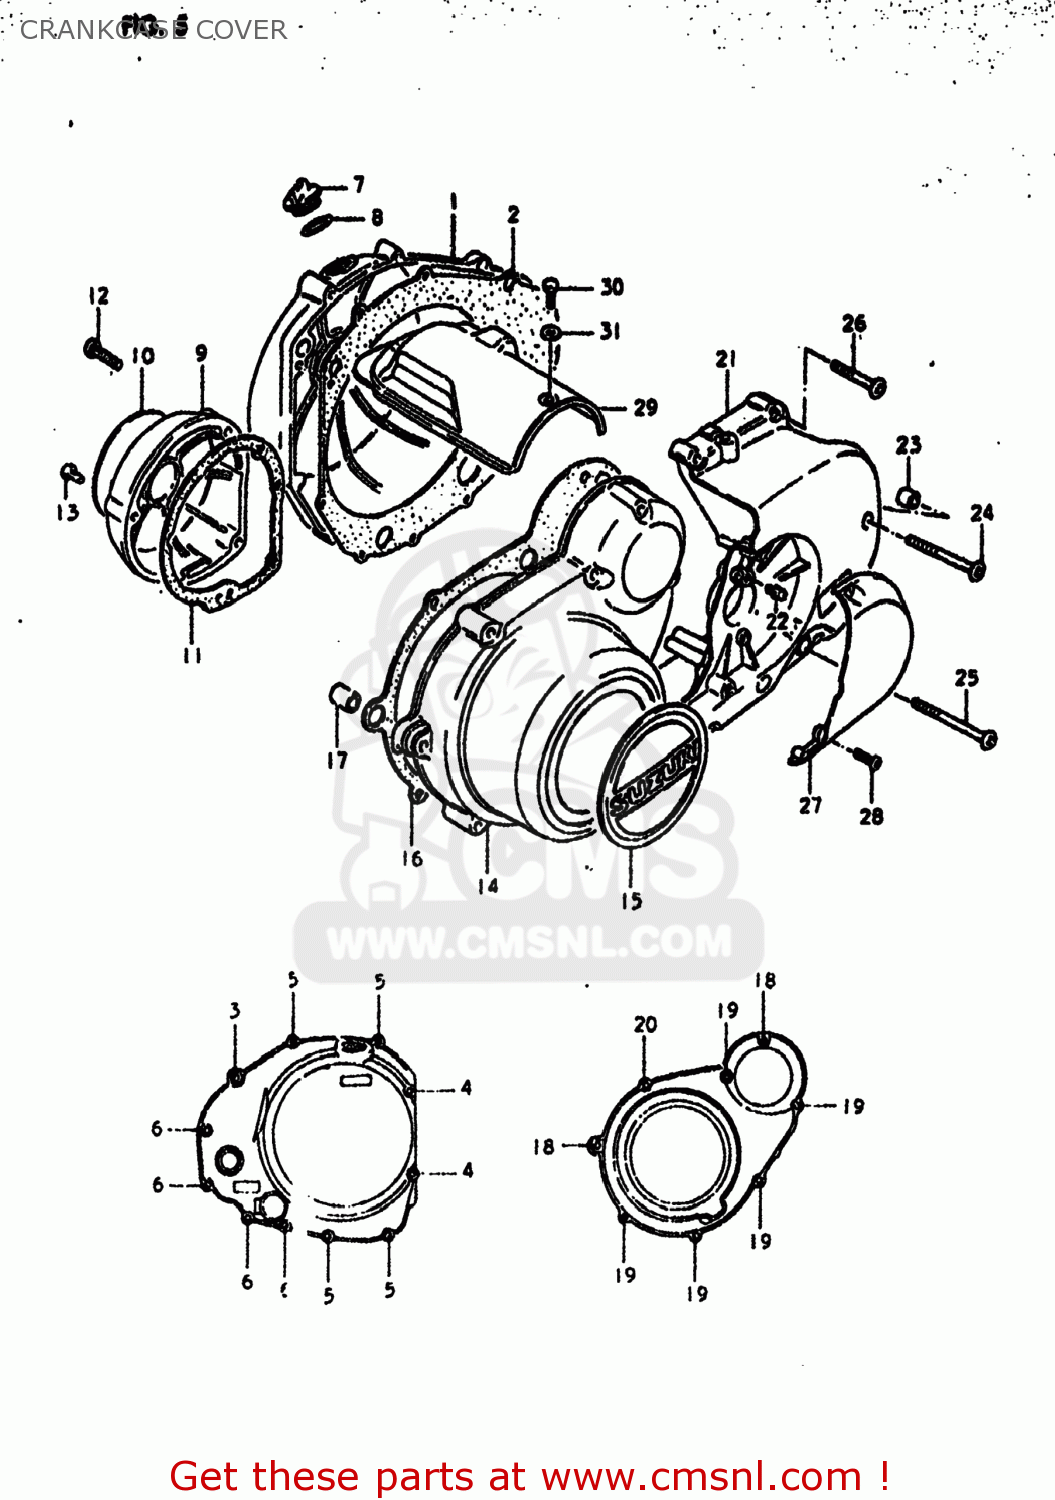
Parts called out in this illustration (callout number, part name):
1	COVER,CLUTCH
2	GASKET,CLUTCH COVER (MCA)
3	SCREW (6X35)
4	SCREW
5	SCREW
6	SCREW
7	CAP
8	O RING(D:2.2,ID:32)
9	COVER,CONTACT BREAKER
10	EMBLEM,CONTACT BREAKER COVER
11	GASKET,CONTACT BREAKER COVER (NAS)
12	SCREW
13	SCREW
14	COVER
15	EMBLEM,MAGNETO COVER
16	GASKET,MAGNETO COVER (MCA)
17	PIN
18	SCREW (6X45)
19	SCREW
20	SCREW (6X35)
21	CRANKCASE SET
22	NIPPLE
23	PIN
24	SCREW
25	SCREW 6X80
26	SCREW 6X30
27	CAP,CLUTCH RELEASE ADJUST
28	SCREW
29	COVER,STARTER MOTOR
30	BOLT
31	WASHER
